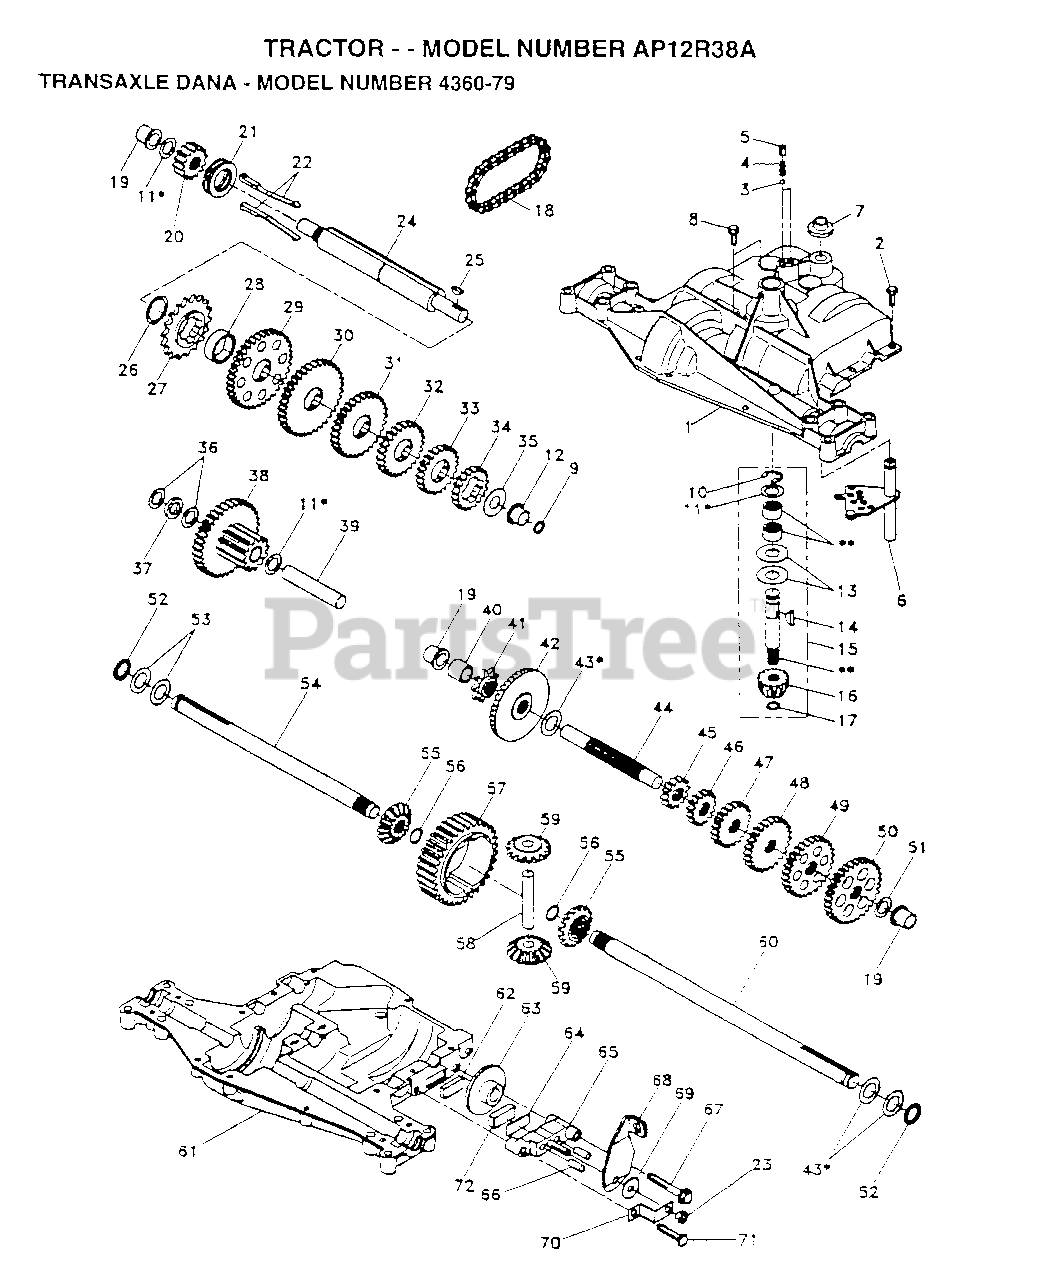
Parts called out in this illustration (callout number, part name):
1	HOUSING UPPER TRN
4	"SPRING, DETENT LT"
5	"SCREW, SET LT"
6	KIT SHIFTER ASM
7	SHIFTER BOOT
8	SCREW TAP W/SEAL
9	SQUARE RING
11	ASM KIT SHIM 4689
12	BEARING FLAN-DANA
13	WASHER T
14	KEY WOODRUFF-DANA
15	AS KIT INPUT SHFT
16	PINION 14T T
17	"RING,RETAINING LT"
18	"CHAIN,24 PTCH LT"
19	BEARING.FLNG.5510
20	GEAR SPUR 14 TTH
21	COLLAR CLUTCH
22	ASM KIT CLTCH KEY
23	NUT.LOCK.5/16-24
24	SHAFT INTERM DANA
25	WOODRUFF KEY
26	"RING,RETAINING LT"
27	SPROCKET 18T T
28	SPACER YT
29	GEAR SPUR 37 TTH
30	GEAR SPUR 35 TTH
32	GEAR 25T LT
33	GEAR SPUR 22 TT
34	SPUR GEAR 19T
35	"WASHER, PLAIN LT"
36	WASHER 025
37	SPACER
38	ASSM GEAR COMB
39	SHAFT IDLER
40	SPACER T
41	SPROCKET 9T LT
43	ASM KIT SHIM
44	SHAFT T
45	GEAR SPUR 12 TTH
46	GEAR SPUR 15 TTH
48	"GEAR, SPUR 25T LT"
49	GEAR 28T T
50	"GEAR, SPUR 31T LT"
51	WASHER 060
52	NEOPRENE WASHER
53	WASHER 031
55	GEAR 15T T
56	"RING,RETAINING LT"
58	SHAFT T
59	GEAR 1ST T
61	HOUSING LOWER TNS
62	PUCK T
63	BRAKE DISC. T
64	SPACER LT
66	PIN T
69	WASHER LT
71	"SCREW, TAPPING LT"
72	PUCK T
